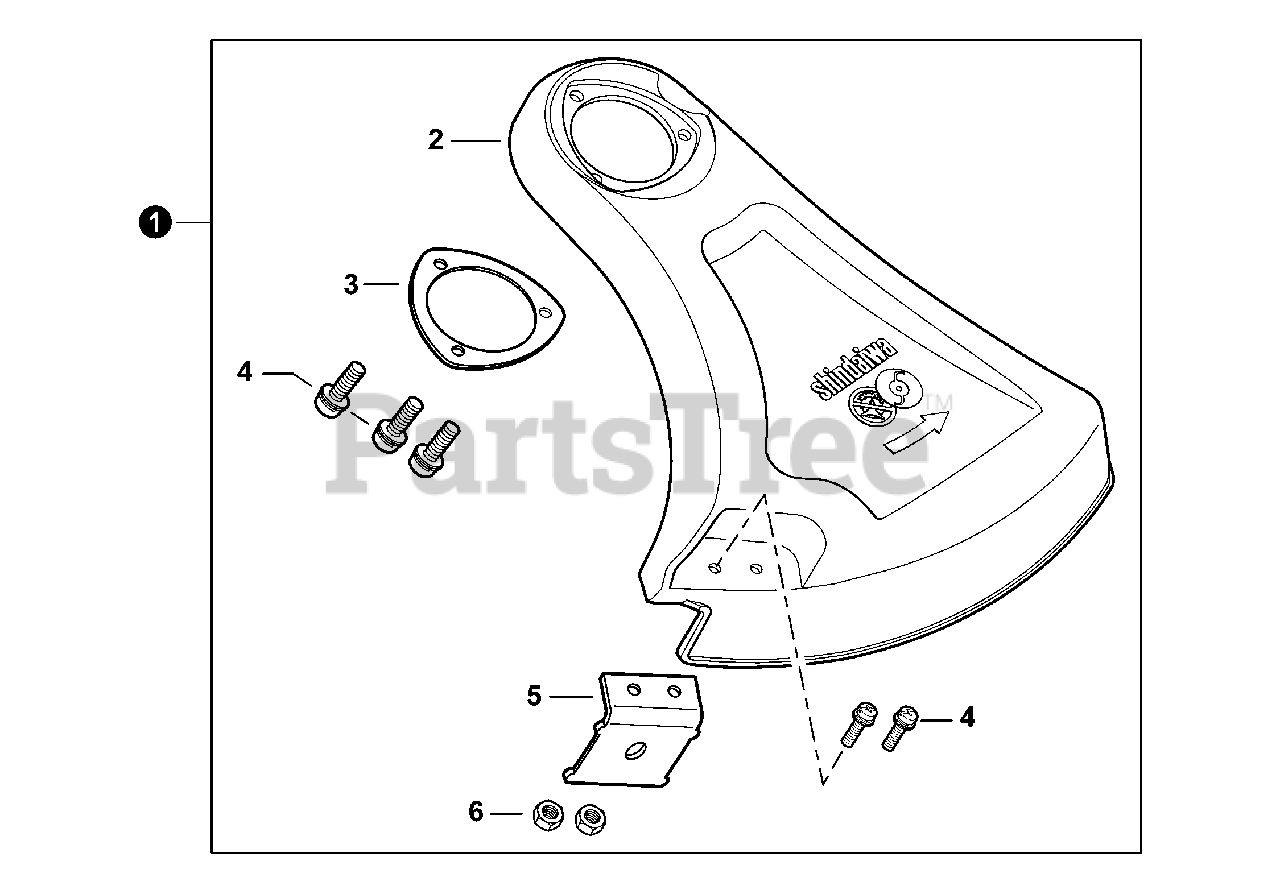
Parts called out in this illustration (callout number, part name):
1	DEBRIS SHIELD ASSY
2	SHIELD, DEBRIS
3	PLATE, SHIELD Ø49.5 MM
4	SCREW 5×16
5	CUTTER, LINE
6	NUT M5
